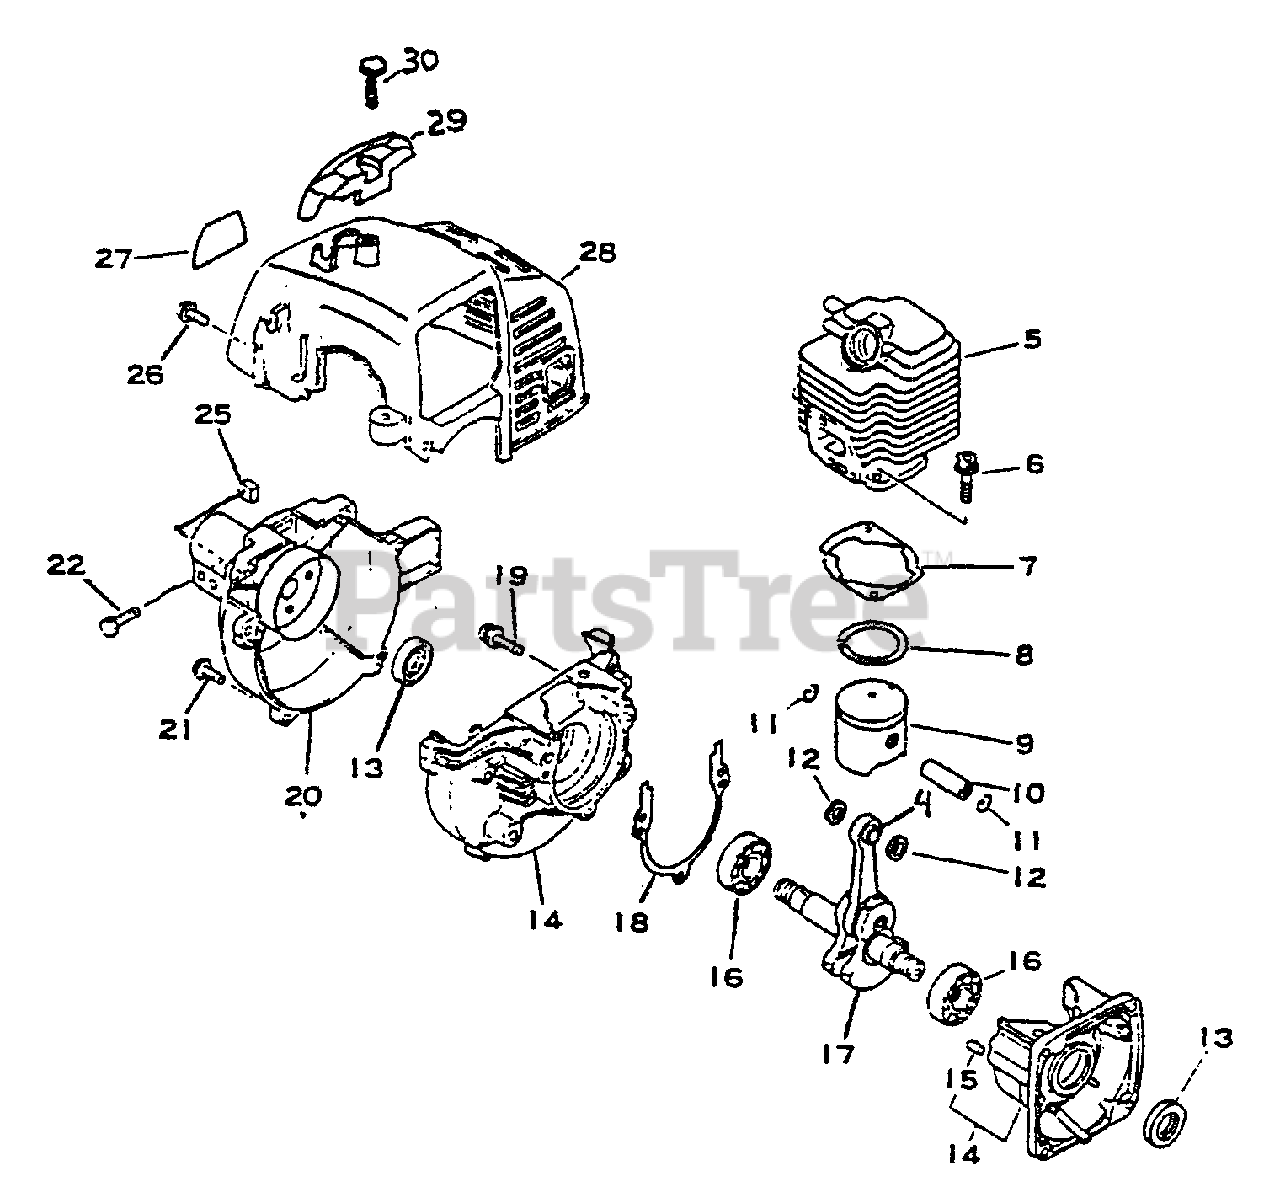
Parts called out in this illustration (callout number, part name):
4	BEARING, NEEDLE
5	CYLINDER
6	SCREW - 5X22
7	GASKET, CYLINDER
8	RING, PISTON
9	PISTON
10	PIN, PISTON
11	RING, RETAINING
12	SPACER, PISTON
13	SEAL, OIL
14	CRANKCASE KIT
15	PIN - LOCATING
16	BEARING, BALL - 6201
17	CRANKSHAFT ASSY
18	GASKET, CRANKCASE
19	SCREW - 5X25
20	FAN CASE ASSY
21	SCREW - 5X18
22	BOLT - 5X28
25	NUT - 5 -- SQUARE
26	SCREW - 4X12
27	LABEL - ECHO
28	COVER, ENGINE
29	GUARD, TOP - BLACK
30	SCREW - 5X16 -- TAPPING
